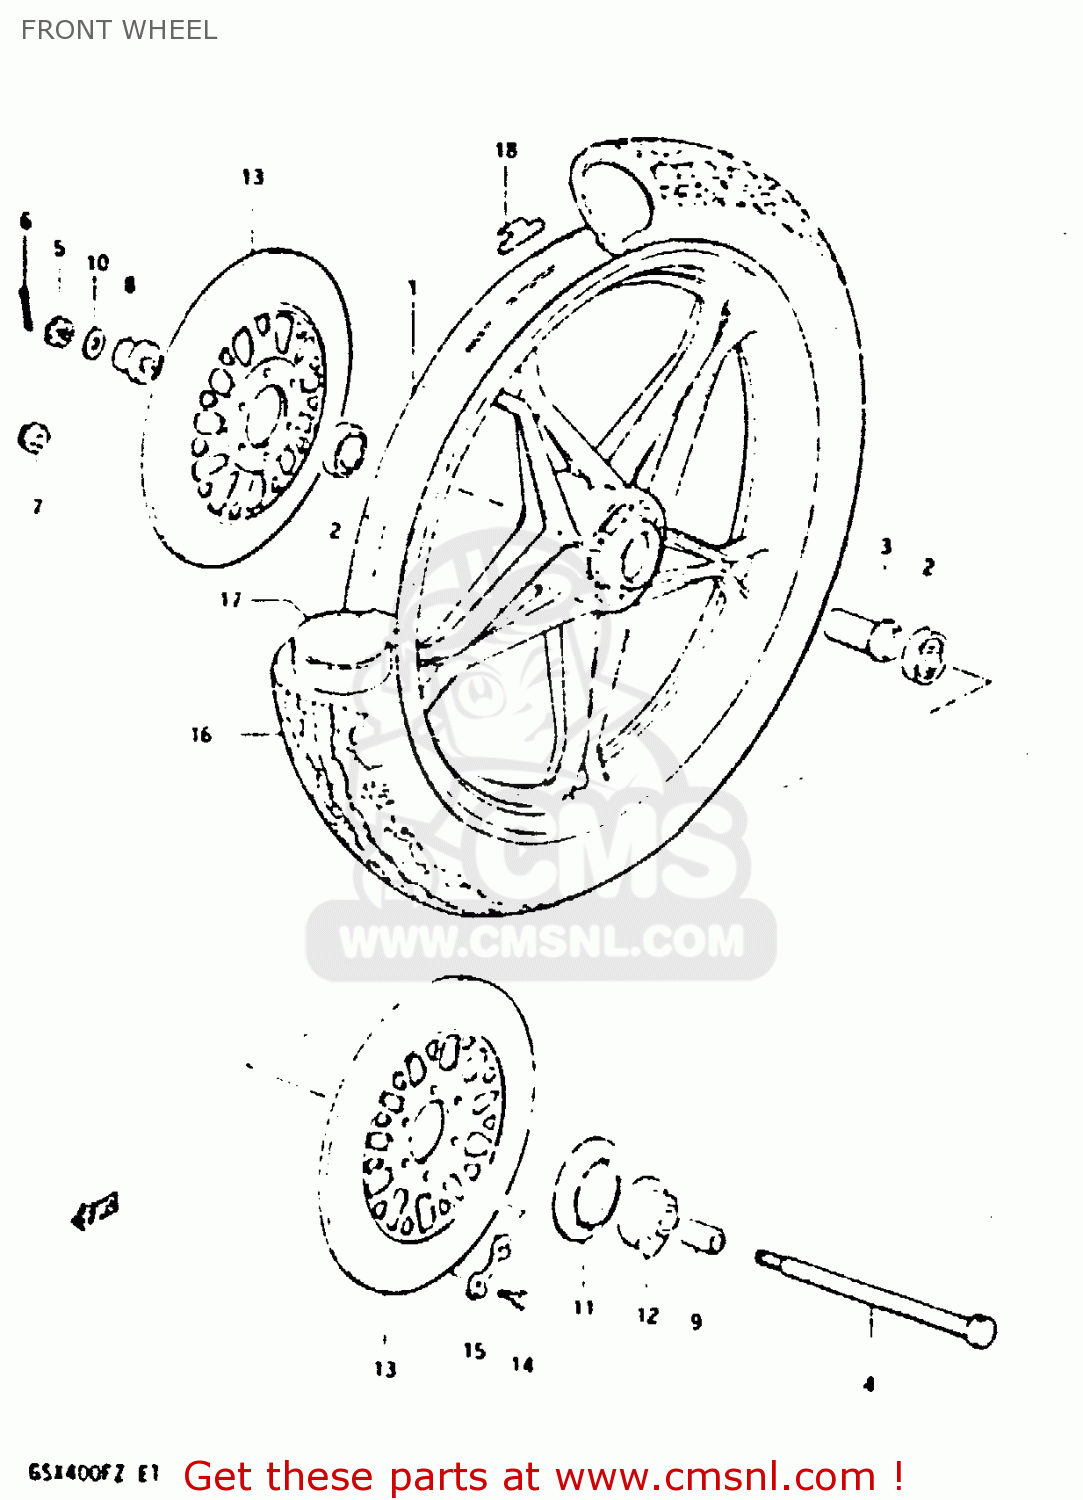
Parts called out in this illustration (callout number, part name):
1	WHEEL, FRONT (19*1.85)
2	BEARING
3	SPACER,FR HUB BEARING
4	AXLE,FRONT
5	NUT 12MM
6	COTTER PIN
8	SPACER,FR HUB BEARING,R
9	SPACER(15X22X30)
10	WASHER
11	DUST SEAL,SPEEDOMETER GEAR BOX
12	BOX ASSEMBLY,SPEEDOMETER GEAR
13	DISK, FRONT BRAKE
14	BOLT(8X25)
15	WASHER
16	TIRE (3.25S19)
17	TUBE,INNER
18	BALANCER,WHEEL
